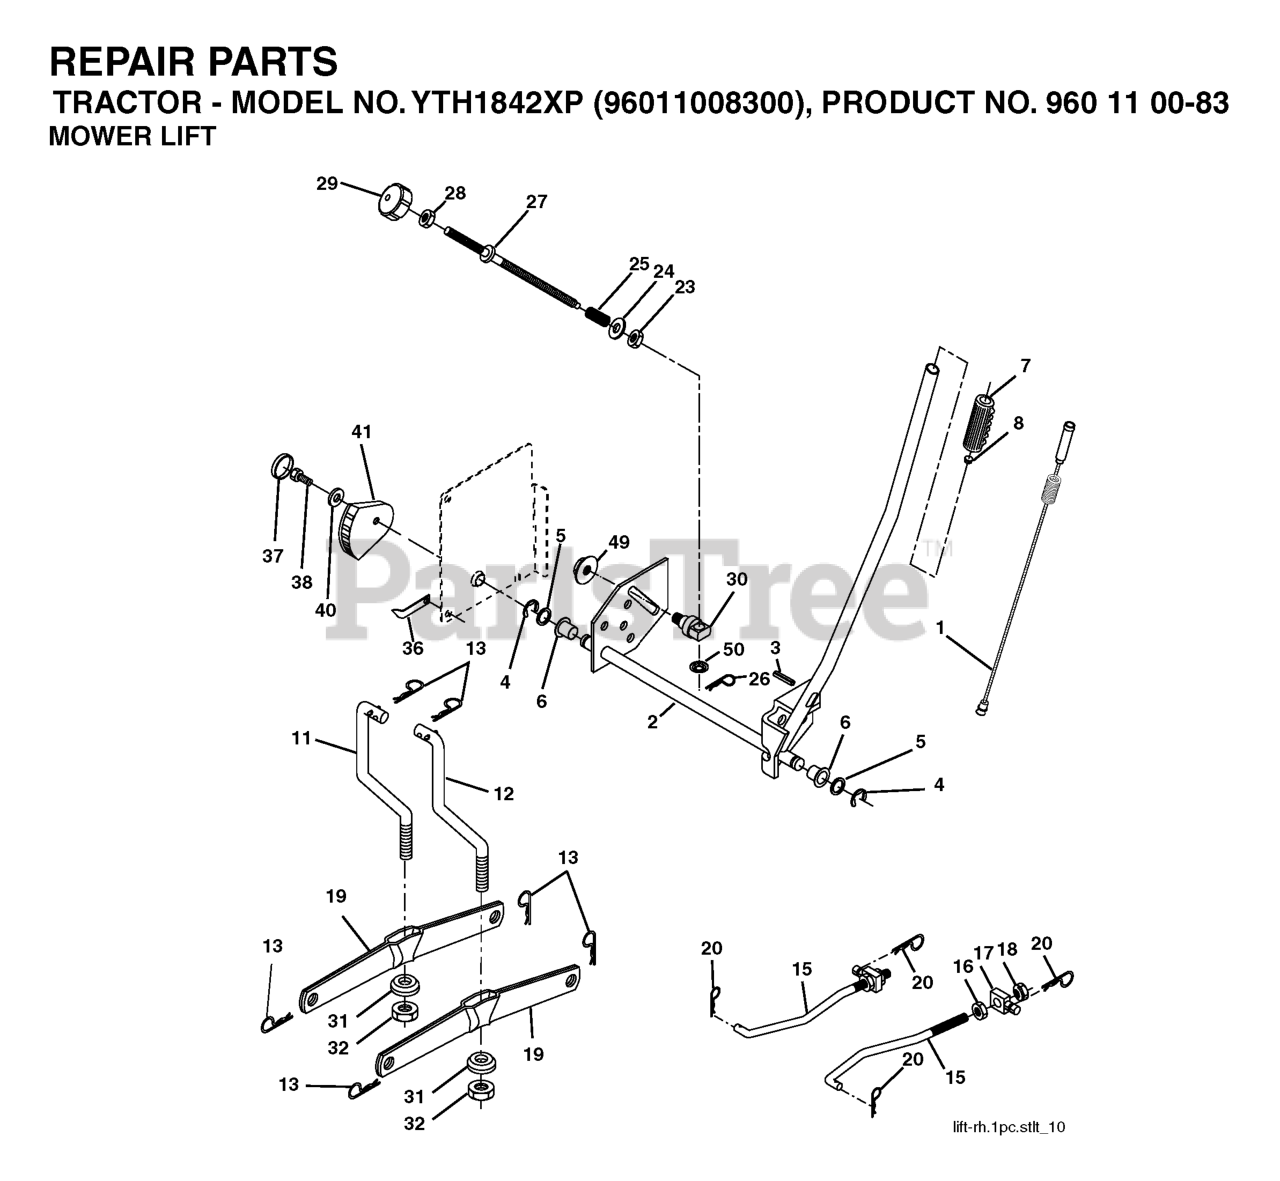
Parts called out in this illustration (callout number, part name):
1	WIRE.ASM.INNER.SP
2	SHAFT.ASM.LIFT.RH.INF
3	PIN.GROOVE.5/16
4	RETAINING RING LT
6	BEARING.NYLON
7	GRIP HANDLE
8	PLUNGER BUT KIT
11	LINK LIFT LH
12	LINK LIFT RH
13	RETAINER-SPRNG RB
15	LINK.SUSPENSION.FRONT
16	NUT.HEX.JAM.1/2-13
18	NUT.LK.W/WSH.1/2.
19	ARM.REAR.SUSPENSION
20	SPRING RETAINER
26	RETAINER CLIP
27	ROD ADJ LIFT
28	NUT
29	KNOB INF 3/8-16
31	BEARING.PIVOT.LIFT
32	NUT CROWNLOCK 3/8-24
36	POINTER, HEIGHT INDICATOR(2 2)
38	SCREW 5/16-18X1
41	IND. HEIGHT STLT
49	NUT
50	NUT PUSH M
